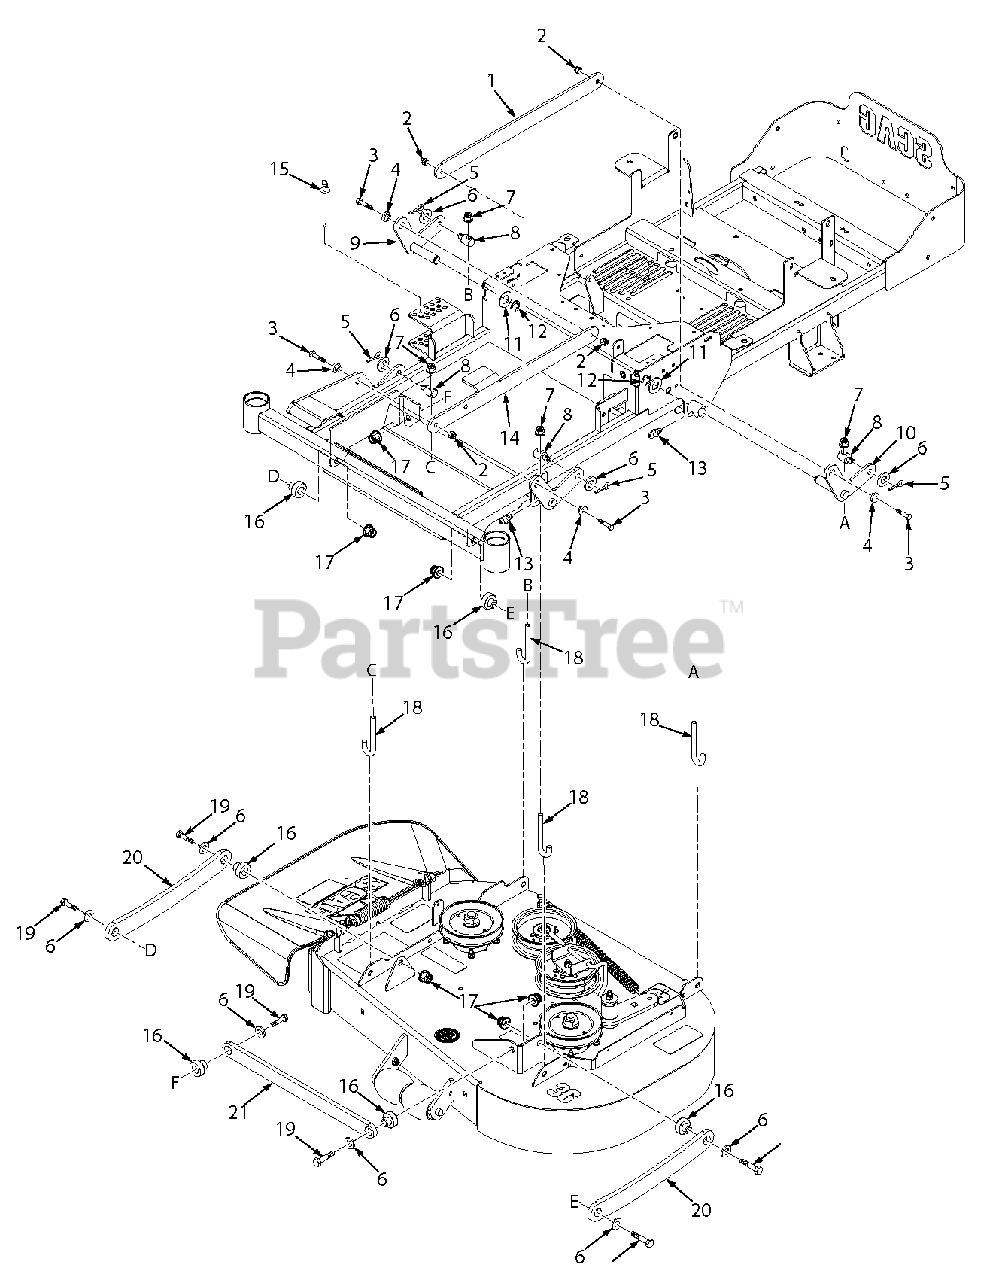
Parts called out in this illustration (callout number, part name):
1	Link, Deck Lift - LH
2	Nut, 3/8-16 Elastic Stop
3	Bolt, Hex Head 3/8-16 x 1-1/4"
4	Bushing
5	Cotter Pin, 3/16 x 1"
6	Flatwasher, 1/2-.531 x 1.062 x .095
7	Nut, 1/2-13 Elastic Stop
8	Joint, Swivel
9	Lift Bellcrank Weldment, RH
10	Lift Bellcrank Weldment, LH
11	Flatwasher, 3/4-.769 x 1.250 x .0598
12	Retaining Ring, .750 "E"
13	Grease Fitting, 1/4-28 Self Tap
14	Link, Deck Lift - RH
15	Pin Assembly, Deck Height
16	Bushing, Deck latch
17	Nut, 1/2-13 Elastic Stop
18	Rod, Deck lift
19	Bolt, Hex Head 1/2-13 x 1-3/4
20	Pull Arm, Deck
21	Lateral Link
